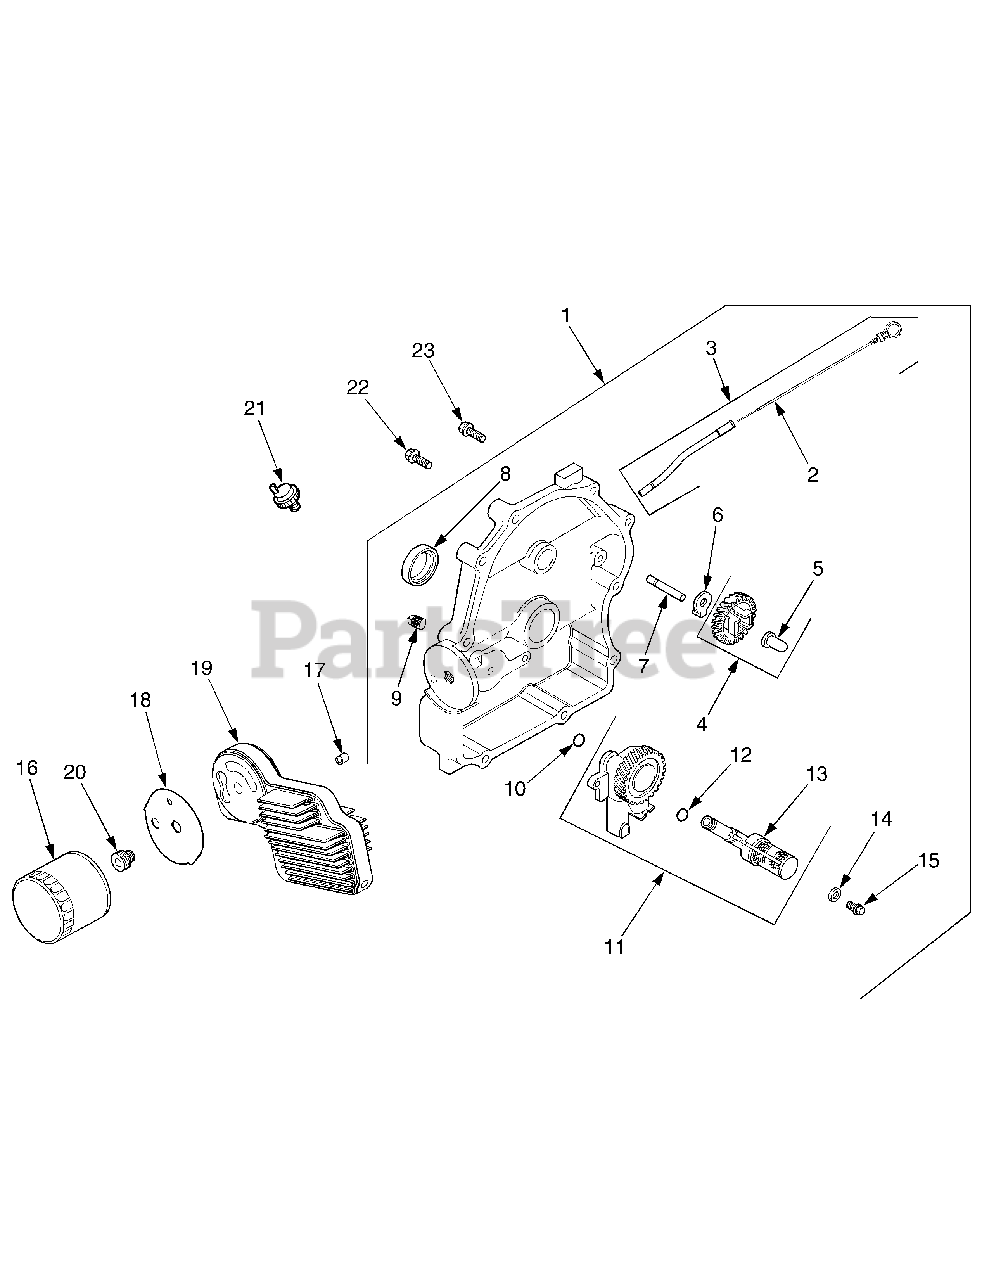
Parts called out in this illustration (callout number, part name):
1	Plate, Closure Assembly (Includes 2-15)
3	Tube, Dipstick (Includes 2)
4	Kit, Governor Gear (Includes 5) ..
5	Pin, Governor Regulating
7	Shaft, Governor Gear
8	Seal, Oil (PTO End)
9	Plug, Pipe 1/8"
11	Oil Pump Assembly (Includes 12,13)
12	O-Ring, Oil Pick-Up
13	Pick-Up, Oil
14	Washer, Plain
15	Screw, Hex Flange M6 x 1 x 25 ..
16	Filter, Oil
17	Pin, Locating
18	Gasket, Adapter
20	Nipple, Oil Filter
21	Switch, Pressure
22	Screw, Hex Flange M8 x 1.25 x 45
23	Nut, Hex Flange, M8 x 1.25
